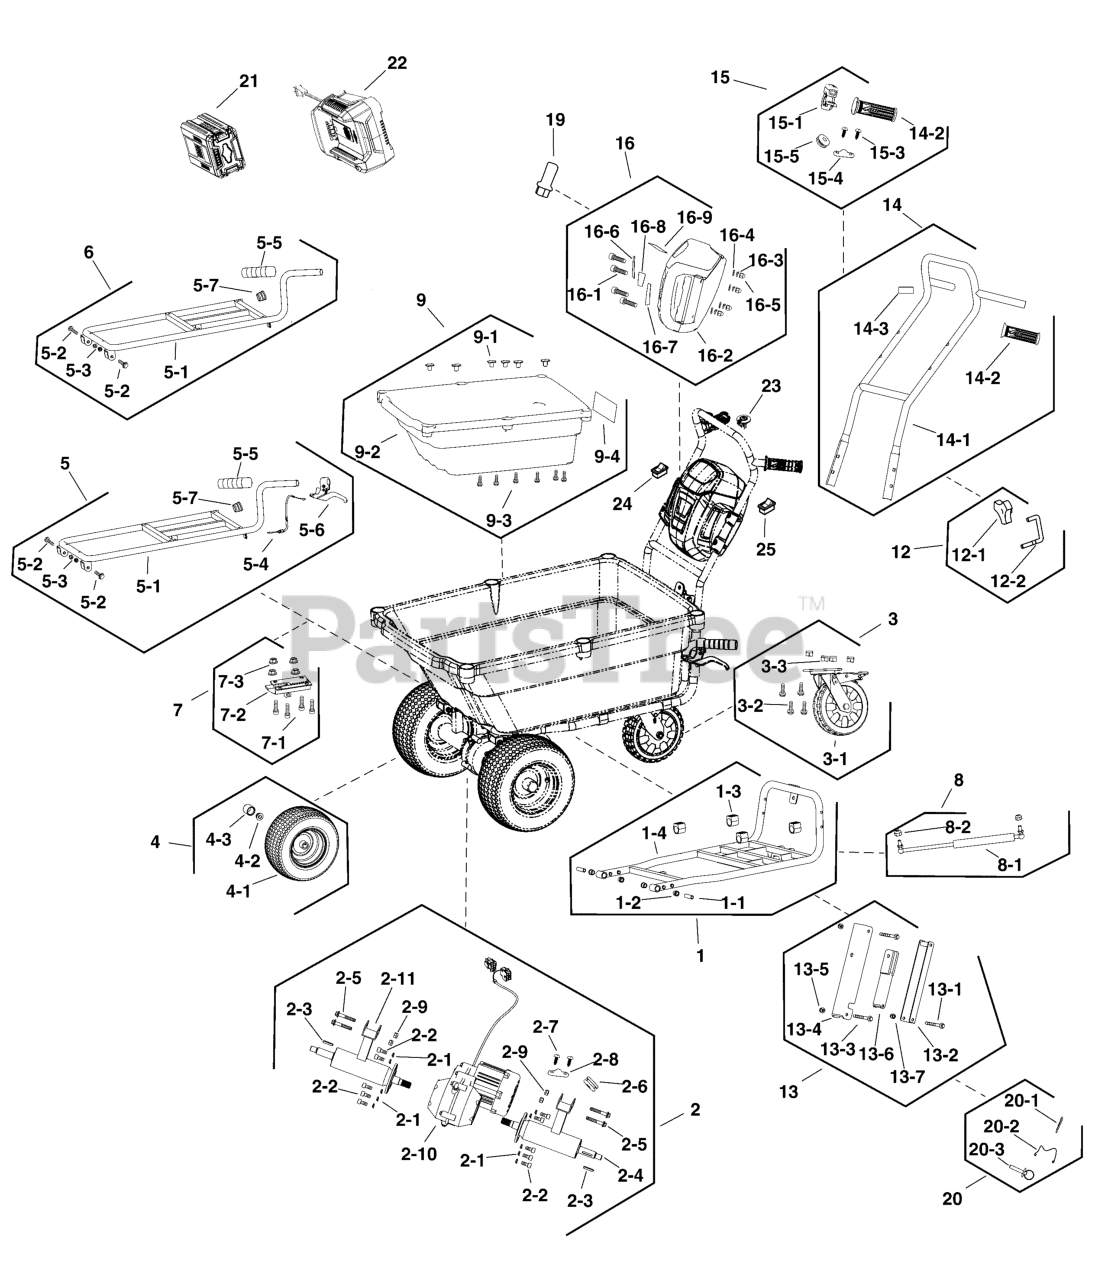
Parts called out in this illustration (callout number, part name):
1	KIT, BOTTOM FRAME
1-1	KIT, BUSHING
1-2	KIT, BUSHING
1-3	KIT, VIBRATION
1-4	BOTTOM FRAME
2	KIT, MOTOR & TRANSMISSION
2-1	WASHER
2-4	AXLE, LEFT
2-6	RUBBER SHEATH
2-8	STRAIN RELIEF
2-10	MOTOR & TRANSMISSION
2-11	AXLE, RIGHT
3	KIT, CASTER
3-1	CASTER, 8 "
4	KIT, TIRE
4-3	AXLE SHEATH
5	KIT, FRAME
5-1	FRAME, BUCKET
5-5	GRIP, HANDLE
5-6	LEVER ASSEMBLY
5-7	KIT, PLUG
6	KIT, FRAME
7	KIT, LOCK
7-2	CLASP, LOCKING
8	KIT, SPRING
8-1	SPRING
9	KIT, BUCKET
9-2	BUCKET, B&S
9-4	DECAL, WARNING
12	KIT, KNOB & PIN
12-1	KNOB
12-2	U-PIN
13	KIT, HITCH
13-2	PLATE, HITCH
13-4	PLATE, HITCH
13-6	PLATE, CONNECTING
14	KIT, HANDLE
14-1	HANDLE
14-2	GRIP, HANDLE
14-3	LABEL
15	KIT, THROTTLE
15-1	THROTTLE
15-4	STRAIN RELIEF
15-5	SHEATH
16	KIT, PANEL
16-2	PANEL
16-3	WASHER, FLAT
16-4	WASHER
16-5	NUT, CAP
16-6	DECAL, LEFT
16-7	DECAL, RIGHT
16-8	DECAL
16-9	LABEL SHEET
19	KIT, SAFETY KEY
20	KIT, LOCK & PIN
20-1	PIN, COTTER
20-2	LINK
20-3	PIN
21	* BATTERY, 2.0, 82V EU/AU
22	* CHARGER, Battery, EU
23	SWITCH, ON/OFF
24	SWITCH, HI/LO
25	SWITCH, FORWARD/REVERSE
